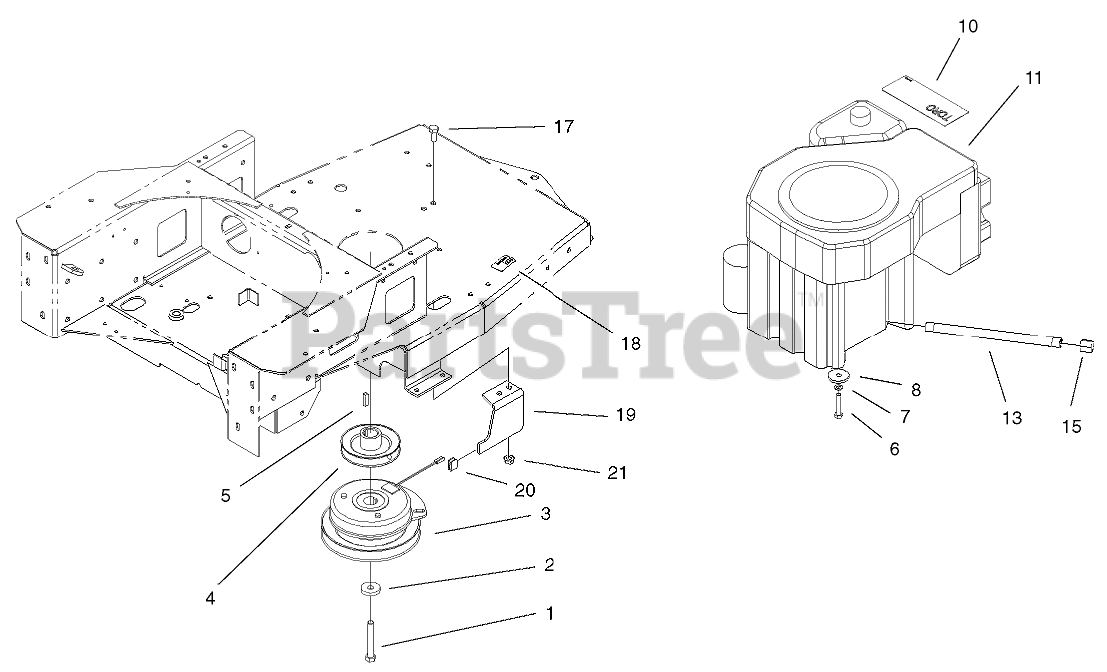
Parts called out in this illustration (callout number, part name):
1	SCREW-HH
2	WASHER
3	CLUTCH
4	PUMP DRIVE PULLEY ASM
6	SCREW-HH
7	WASHER-LOCK
8	SPACER-STEEL
10	Decal-Engine Kohler
13	NIPPLE-PIPE
15	CAP-PIPE
17	SCREW-HH
18	DECAL-SURFACE, HOT
19	STOP-CLUTCH
20	BUMPER
21	NUT-HF
